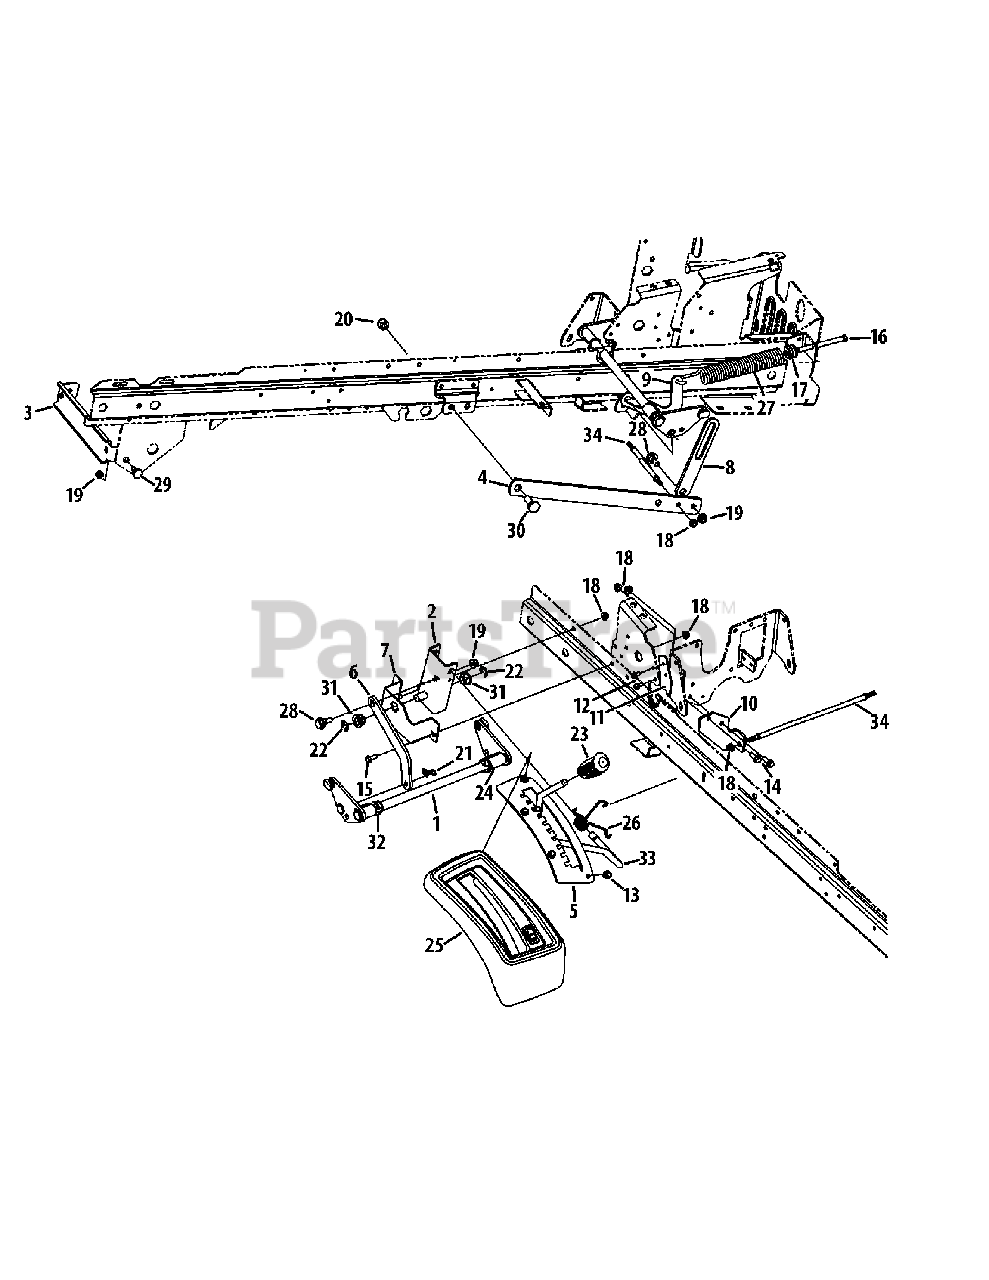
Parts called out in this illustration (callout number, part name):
1	Manual Lift Shaft Assembly
2	Manual Lift Lever Bracket Assembly
3	Front Hanger Bracket
5	Manual Lift Index Bracket
6	Manual Lift Link Plate
7	Manual Lift Lever Mount Bracket
8	Plate-Lift Link
9	Extension Spring Plate
10	Sway Bar Mount Bracket
11	Bearing Stop Plate
12	Hex Washer Screw, 1/4-20 x .500
13	Hex Washer Screw, 5/16-18 x .625
14	Hex Washer Screw, 5/16-18 x .875
15	Hex Screw, 5/16-18 x .75
16	Hex Screw, 3/8-16 x 4.25
17	Spring Insert
18	Flange Lock Nut, 5/16-18
19	Flange Lock Nut, 3/8-16
20	Hex Lock Nut, 1/2-13
21	Bow-Tie Cotter Pin
22	E-Ring, .625
23	Cub Grip
25	Lif Manual Cover
26	LH Torsion Spring
27	Extension Spring, 1.485 x 9.68
28	Shoulder Screw, 3/8-16 x .562 x .360
29	Shoulder Screw, 1/2 x .29
30	Shoulder Screw, 1/2-13 x .625 x .36
31	Hex Flange Bearing
32	Hex Flange Bearing
33	Manual Lift Handle Rod
34	Anti-Sway Deck Rod
